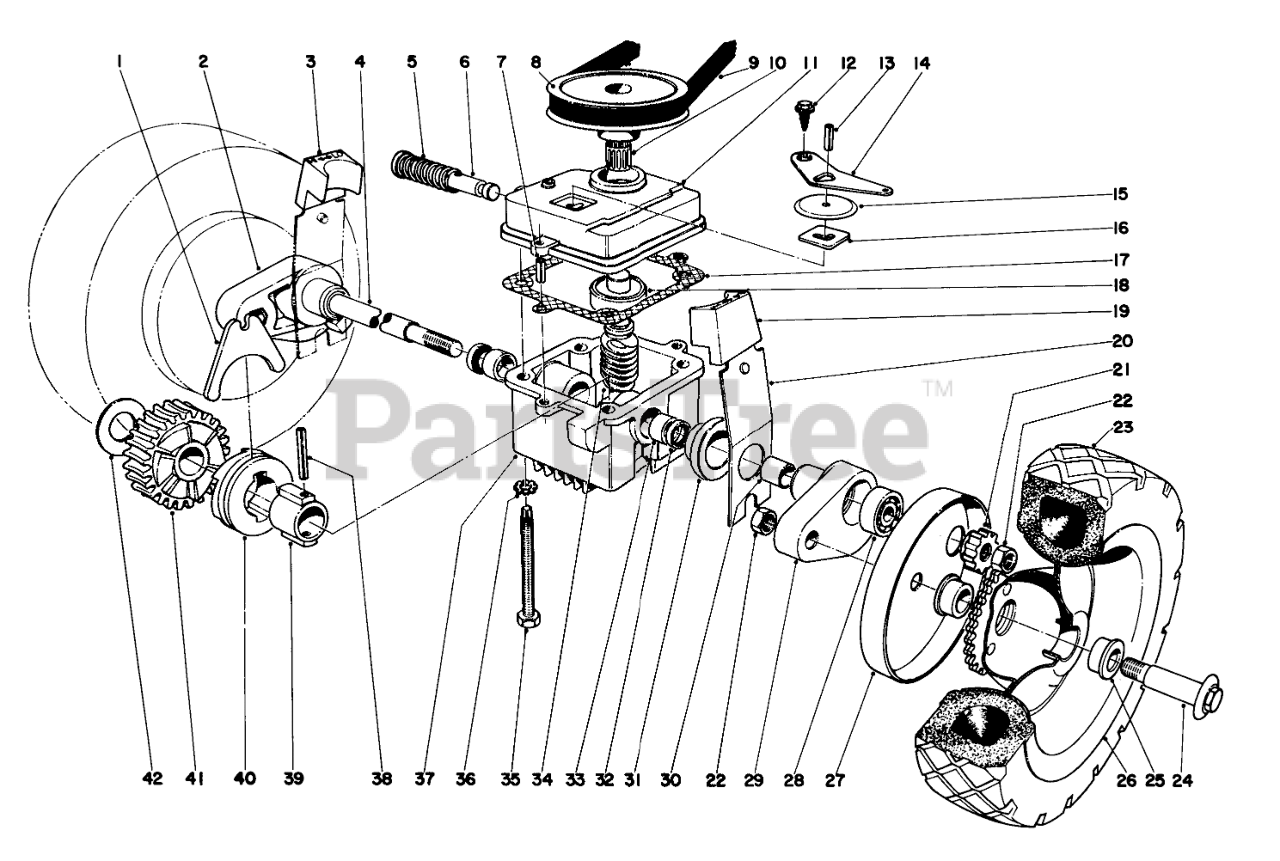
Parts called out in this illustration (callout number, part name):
1	SHIFTER FORK
2	Pivot Arm (Incl. Reference #30)
3	Arm Knob
4	DRIVE SHAFT
5	SPRING
6	Shift Rod
7	3/16 X 1/2 ROLL PIN
8	PULLEY
9	V BELT
10	Tolerance Ring
11	GEAR CASE COVER
12	Screw
13	PIN-ROLL
14	SHIFTER ARM
15	TRANS DUST COVER
16	LATCH PLATE
17	GASKET
18	Bearing
19	Arm Knob
20	Spring Arm
21	PINION GEAR
22	Nut
24	Wheel Bolt
25	FLANGE BUSHING
26	Wheel (Incl. Ref. #25)
27	Wheel Cover
28	.375 RPP BALL BEARING
29	Pivot Arm (Incl. Ref. #30)
30	BUSHING
31	End Cap
32	Seal
33	Bushing
34	Worm Shaft
35	Screw
36	WASHER-LOCK/EXT
37	Gear Case (Incl. Ref. #33)
38	Roll Pin
39	SLEEVE
40	Clutch
41	Worm Gear
42	THRUST WASHER
